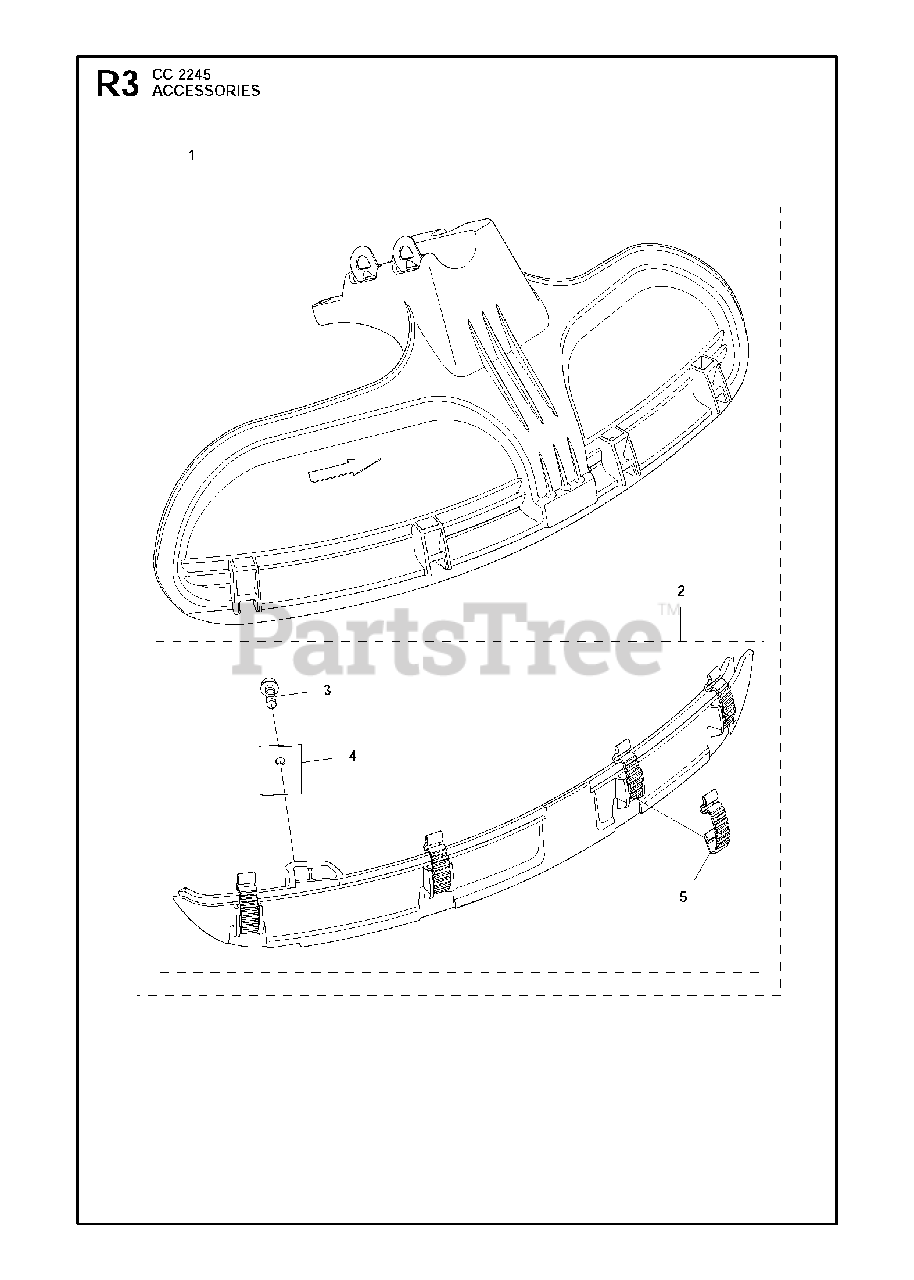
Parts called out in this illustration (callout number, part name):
1	COMBINATION GUARD
3	SCREW
4	LINE CUTTER
5	BUCKLE
